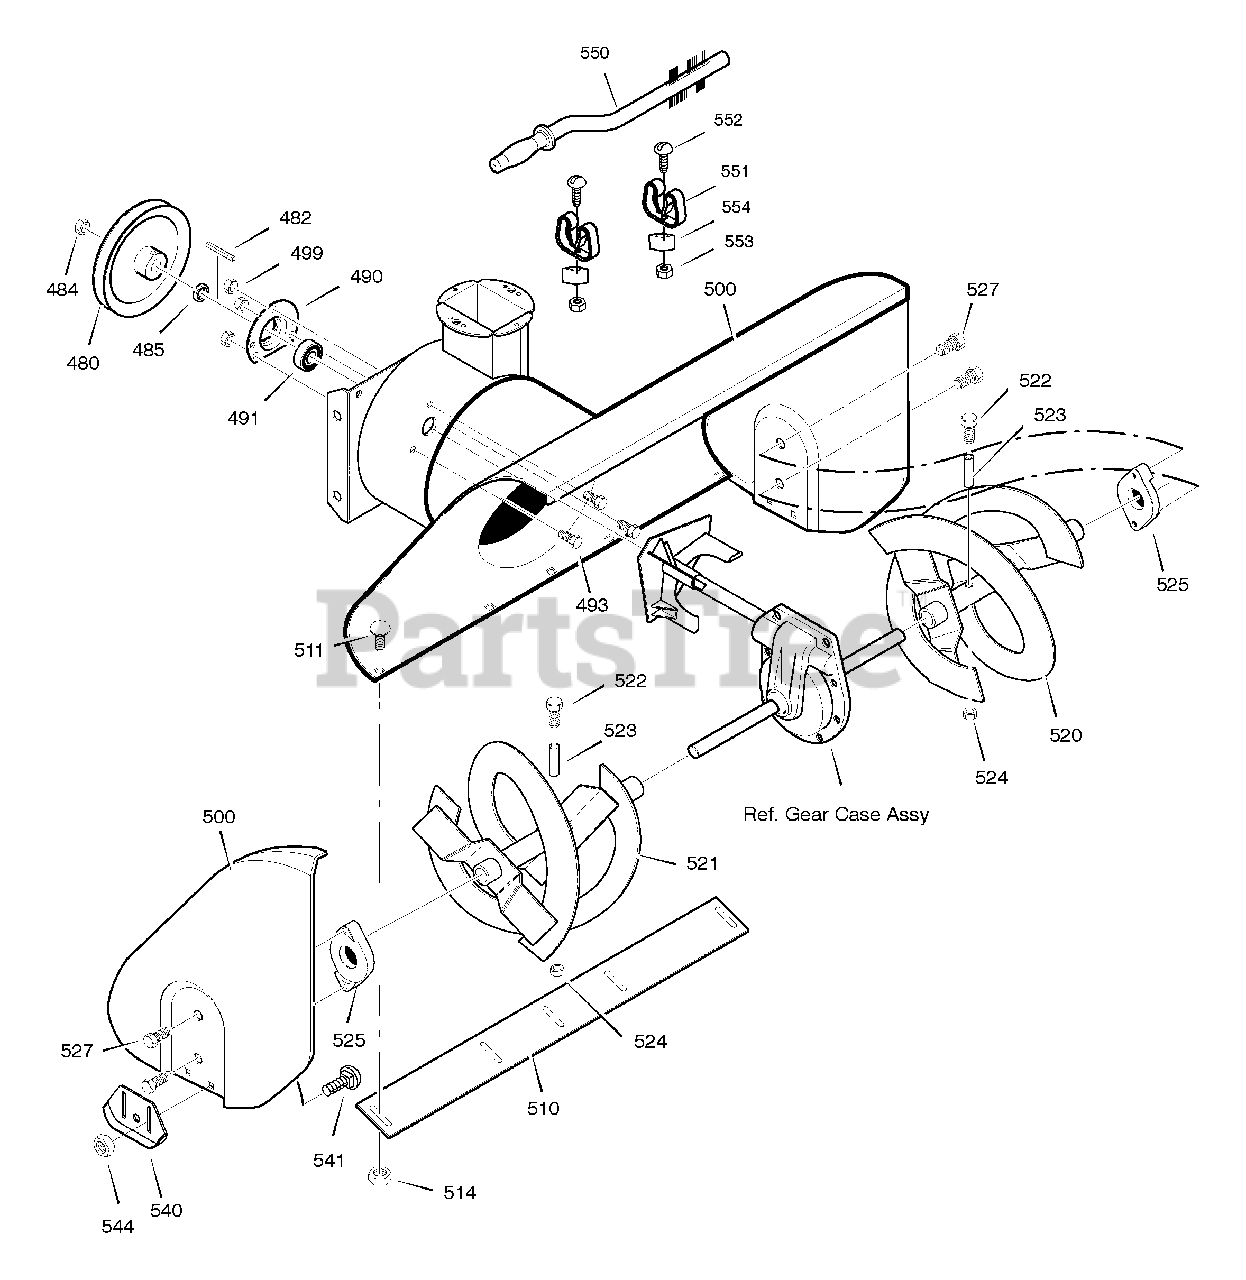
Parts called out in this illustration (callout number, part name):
480	PULLEY, 4L 8.40 OD
482	KEY, SQUARE 3/16x3/4
484	NUT, 1/2-20
485	SPACER, FRICTION PULLEY
490	RETAINER, BALL BRNG
491	BEARING, BALL
493	BOLT, HEX 5/16-18x0.75
499	NUT, 5/16-18 HEX
500	HOUSING, ASSY
510	BLADE, SCRAPER
511	BOLT, 5/16-18x0.75
514	NUT, 5/16-18
520	AUGER, ASSY, LH
521	AUGER, ASSY, RH
522	SCREW, 1/4-20x1.75
523	SPACER, SLEEVE
524	NUT, 1/4-20
525	BEARING, FLANGE
527	SCREW, 5/16-18 x 0.75
540	SKID, HEIGHT ADJUST
541	BOLT, 5/16-18x0.75
544	NUT, 5/16-18
550	BRUSH, CLEANOUT
551	CLIP, RETAINER
552	SCREW
553	NUT
